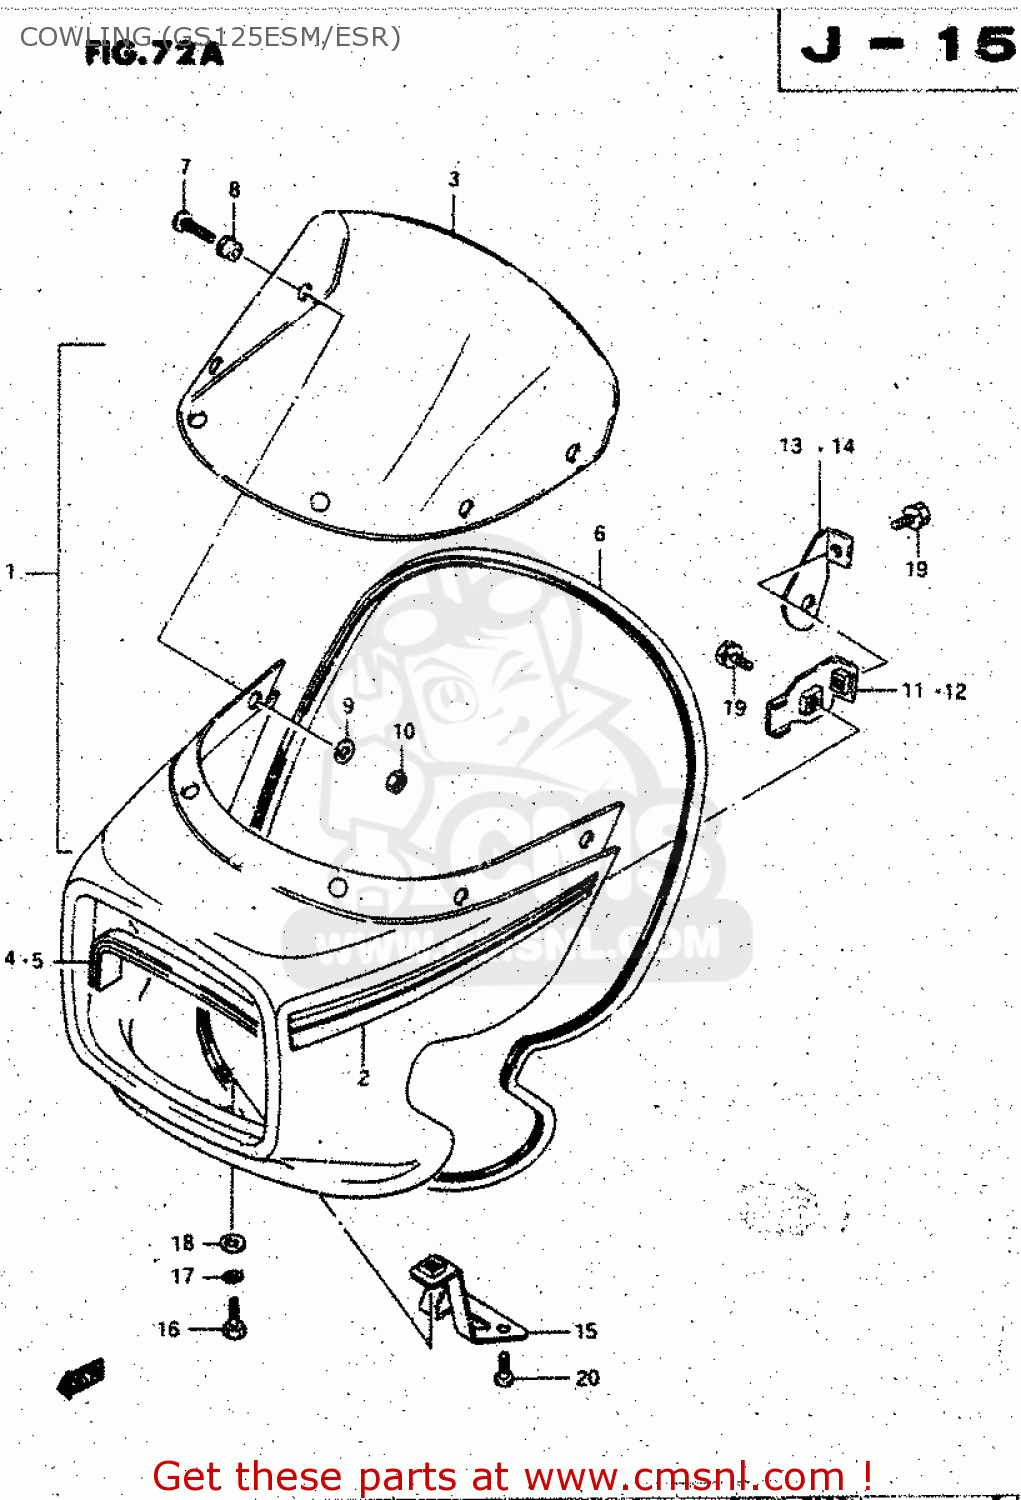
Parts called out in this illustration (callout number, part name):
1	COWLING ASSY (RED)
2	TAPE SET
3	WINDOW,COWLING
4	MOLDING,HEADLAMP GRILL
5	MOLDING,HEADLAMP GRILL
6	MOLD,COWLING
7	SCREW(5X12)
8	CUSHION
9	WASHER
10	NUT
11	BRACE, COWLING RH
12	BRACE, COWLING LH
13	BRACKET,COWLING FITTING,R
14	BRACKET,COWLING FITTING,L
15	BRACKET,COWLING LWR
16	BOLT
17	WASHER,LOCK
18	WASHER (6.5X18X1.6)
19	BOLT
20	SCREW
